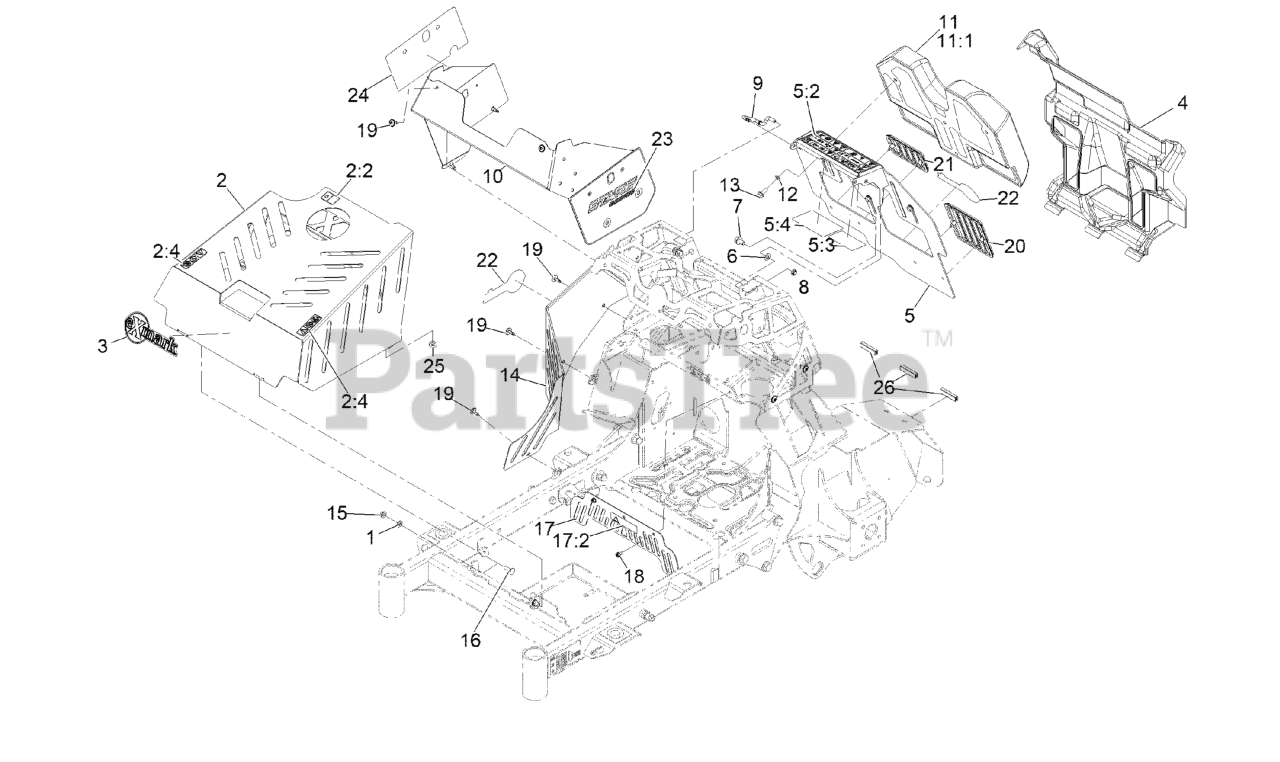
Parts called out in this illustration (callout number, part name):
1	SPACER-NYLON
2	ASM-COVER W DECALS
2:2	DECAL-WARNING
2:4	DECAL-NO STEP/RIDERS
3	DECAL, EXMARK LOGO
4	COVER-REAR STE
5	ASM, PAD BACKING W/ DECALS
5:2	DECAL-WARNING
5:3	DECAL-DRIVE RELEASE
5:4	DECAL-SERVICE AID SM
6	WASHER-THRUST
7	SCREW-HHF
9	ROD, PROP
10	SKIN, TOWER
11	PAD-THIGH
11:1	COVER, PAD
12	WASHER-BELLEVILLE
13	SCREW-HHF
14	COVER, RT SIDE
16	BOLT-CARR
17	ASM, BELT GUARD W/ DECAL
17:2	DECAL-WARNING
18	SCREW-HWH
19	SCREW, TORX
20	PAD, KNEE, LT
21	PAD, KNEE, RT
22	DECAL-EXMARK LOGO
23	DECAL-STARIS LOGO LT
24	Decal-Staris Logo Rt
26	STRIP-SEAL 2.13
